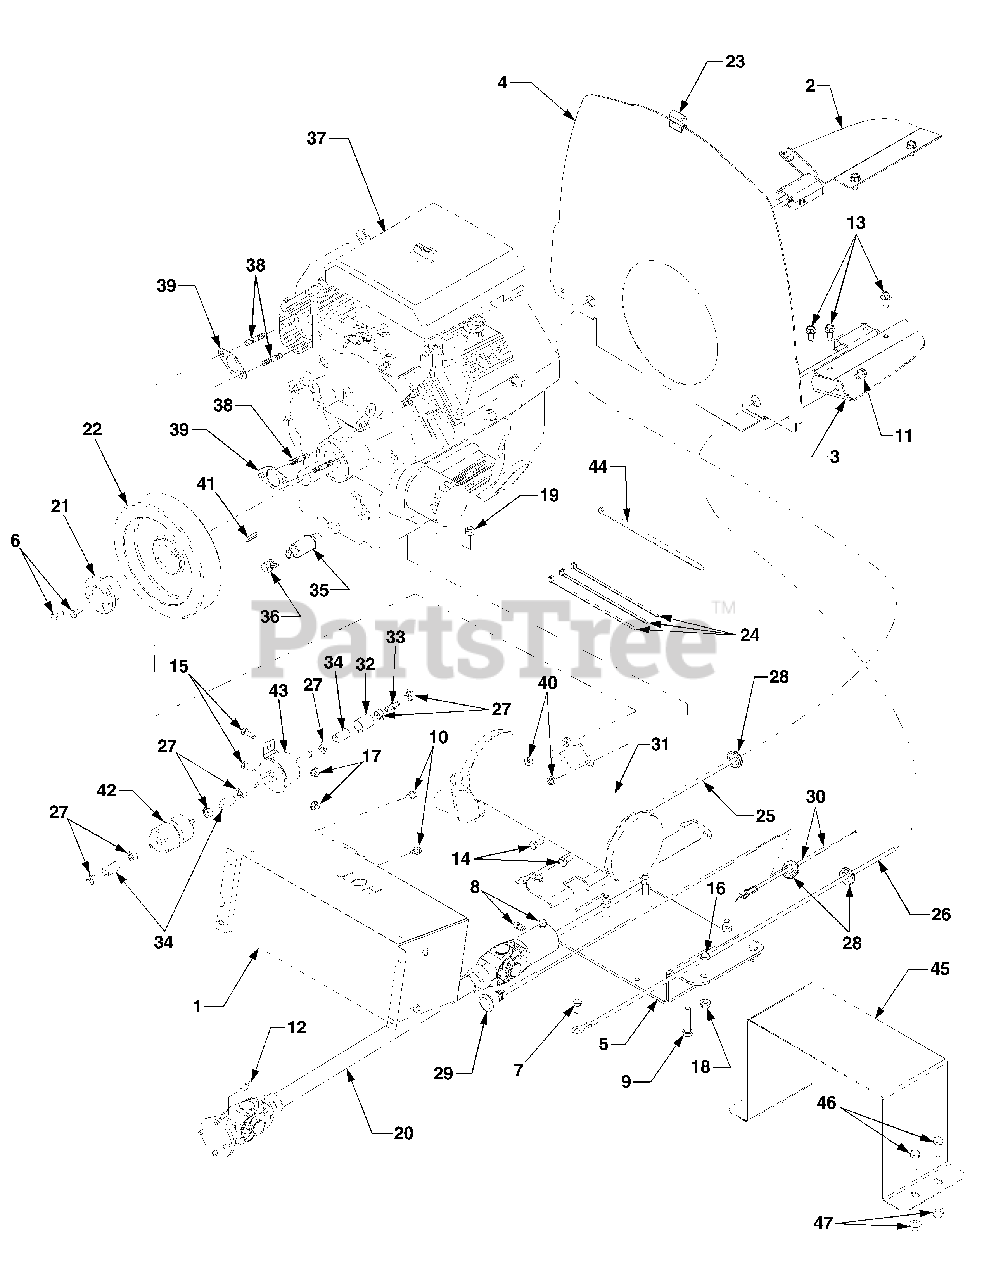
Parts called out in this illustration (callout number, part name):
1	Shield, Heat
2	Plate, Baffle LH
3	Plate, Baffle, RH
4	Plate, Air Baffle
4	Graphic, Battery Warning
5	Plate, Enging Mounting
6	Screw, Hex Cap, 1/4-28 x .625 GR5
7	Screw, Hex Cap, 5/16-24 x .625 GR5
8	Screw, Square Hd. Set, 3/8-16
9	Screw, Hex Cap, 3/8-24 x 1.75 GR5
10	Screw, Hex Wash Hd Tapp 1/4-20 x .5
11	Screw, Hex Wash Hd Tapp 5/16-18 x .5
12	Screw, Socket Hd Cap, 1/4-20 x .62 GR8
13	Screw, Hex Wash Hd Tapp 5/16-18 x .75
14	Screw, Hex Cap, M8-1.25 x 16 GR8
15	Screw, Hex Cap, 1/4-20 x .75
16	Screw, Hex Cap, 5/16-18 x .875 GR5
17	Nut, Hx. Insert Flange Lck, 1/4-20 GRF
18	Nut, Hx. Insert Flange Lck, 5/16-18 GRF
19	Nut, Hex Lock, 3/8-24 GRB
20	Shaft, Drive
21	Bushing, D Type
22	Flywheel
23	Seal, Heat Baffle, 90in.
24	Tie, Cable
25	Wire, Battery Pos.
26	Wire, Battery Neg.
27	Clamp, Hose
29	Cable, Choke Control
30	Cable, Throttle Control
32	Sleeve, Fuel Line
33	Fitting, Reducer, 5/16 - 1/4
34	Fuel Line 5/16 ID, 65in
35	Drain, Engine Oil
36	Cap, Drain
38	Stud, M8 - 1.25 x 33MM
39	Gasket, Exhaust
40	Nut, Hex, M8 x 1.25
41	Key, Sqare, 1/4 x 1.5
42	Filter, Fuel
44	Tie, Cable
47	Nut, Hx. Insert Flange Lck, 3/8-16 GRF
